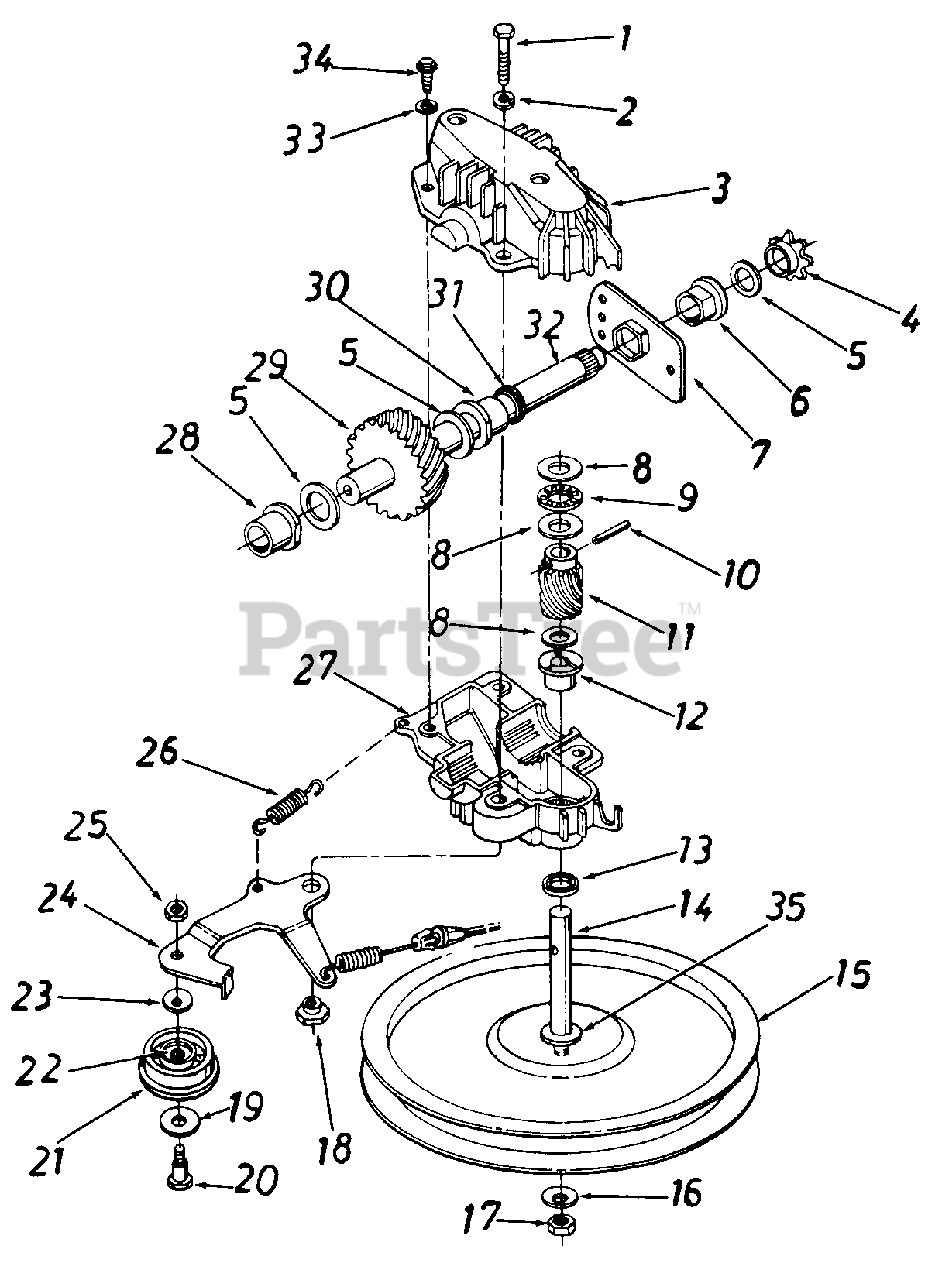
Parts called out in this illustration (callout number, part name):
1	Hex Bolt 1/4-20 x 1.25" Lg.*
2	L-Wash. 1/4" I.D.*
3	Upper Transmission Hsg. Half
4	#48 Sprocket 7 Tooth x 1/2 Pitch
5	Fl-Wash. 518" I.D. x .030
6	Hex Flange Brg. .631" I.D.
7	Hex Bearing Cup
8	Thrust Wash. .382" I.D. x .70" O.D.
9	Thrust Bearing .375" I.D. x .812" O.D.
10	Spring Pin Spir. 1/8" x .62" Heavy
11	11 Tooth Helical Gear
12	Flange Bearing
13	Oil Seal
14	Pulley-Transmission Shaft .375 O.D.
15	Fl-Pulley 5.06" O.D.
16	Bell-Wash. .265" I.D. x .75"
17	Hex Lock Nut 1/4-28 LH Thd.
18	Shld. Spacer .375" Dia. x . 1 70
19	Fl-Wash. .390" I.D. x 1.0"
20	Shld. Bolt .375" Dia. x .40"
21	Fl-Idler Plastic 1.50" Dia. x .48
22	Needle Brg. .375" x .31
23	Bell-Wash. .265" .D. x 75"
24	Idler Brk't. Ass y.
25	Hex Patch L-Nut 1/4-28 Thd.
26	Extension Spring 1.12" Lg.
27	Lower Transmission Hsg. Half
28	Flange Bearing .566 Dia.
29	33 Tooth Helical Gear
30	Flange Bearing .629 Dia.
31	Oil Seal .625 Dia.
32	Gear Sprocket Shaft
33	L-Wash. #10
34	Hex B-Tap Scr. #10 x .62"
35	Hex Washer .26" x .88"
